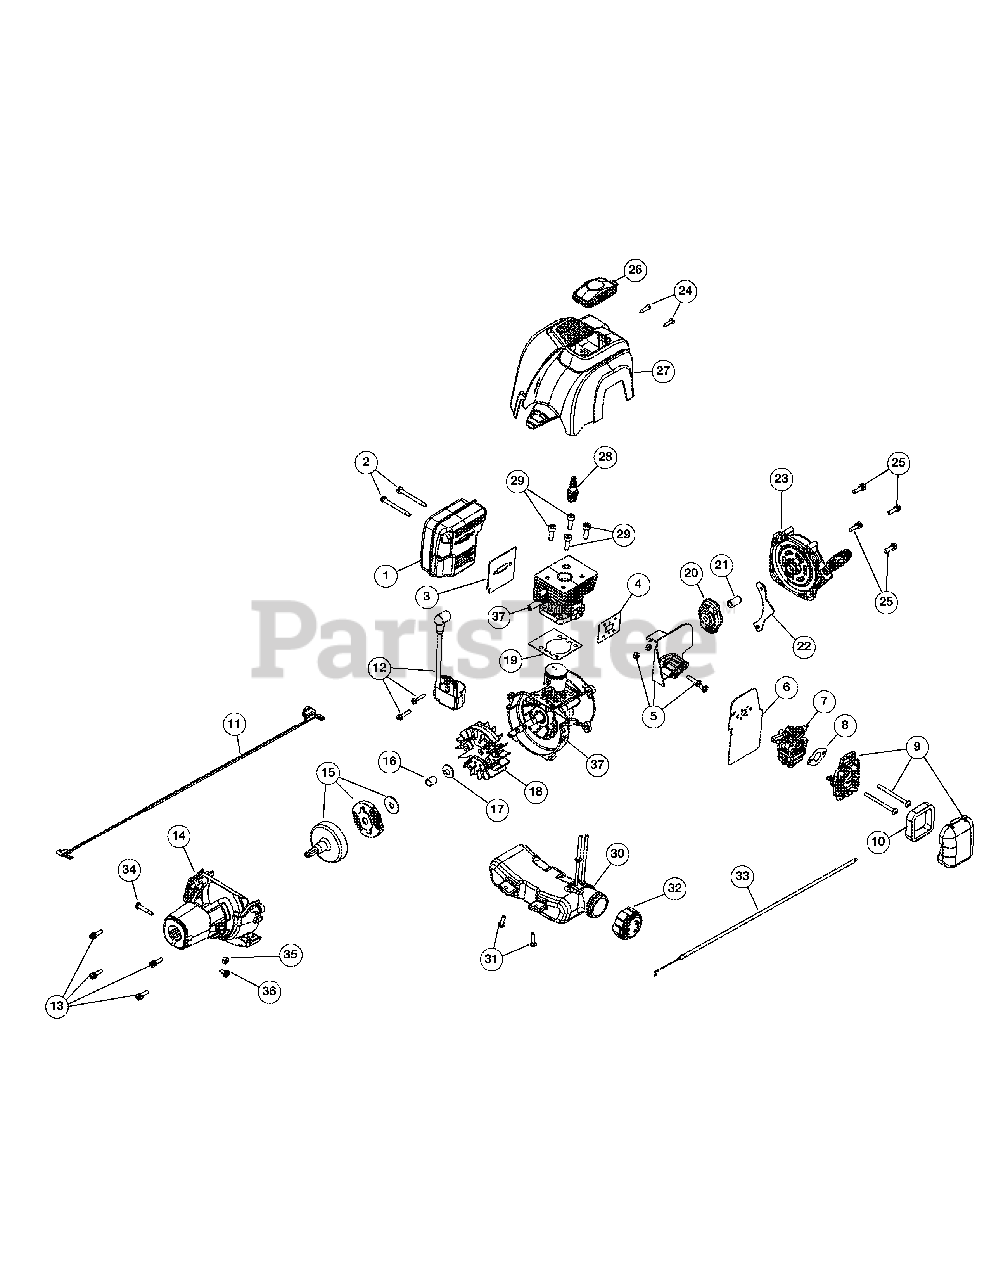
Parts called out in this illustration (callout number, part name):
1	Muffler Assembly
2	Mufler Bolts
3	Muffler Gasket
5	Insulator Assembly (Incl. Ref No. 4)
6	Heat Shield
7	Carburetor
8	Carburetor Gasket
9	Aircleaner Assembly (Incl. Ref No. 10)
10	Aircleaner Filter
12	Module Assembly
13	Clutch Cover Screws
14	Clutch Cover Assembly (Incl. Ref No. 13, 34-36)
15	Clutch Assembly
18	Flywheel Assembly
19	Cylinder Gasket
20	Pawl Assembly
21	Electric Starter Adapter
22	Starter Cover Guard (Incl. Ref No. 25)
23	Starter Assembly (Incl. Ref No. 22 & 25)
26	Spark Plug Cover
27	Engine Cover
28	Spark Plug
29	Cylinder Screws
30	Fuel Tank Assembly (Incl. Ref No. 31 & 32)
31	Fuel Tank Screws
33	Throttle Cable
34	Screw
36	Anti-Rotation Screw
37	Shortblock (Incl. Ref No. 12, 16-19 & 28-29)
